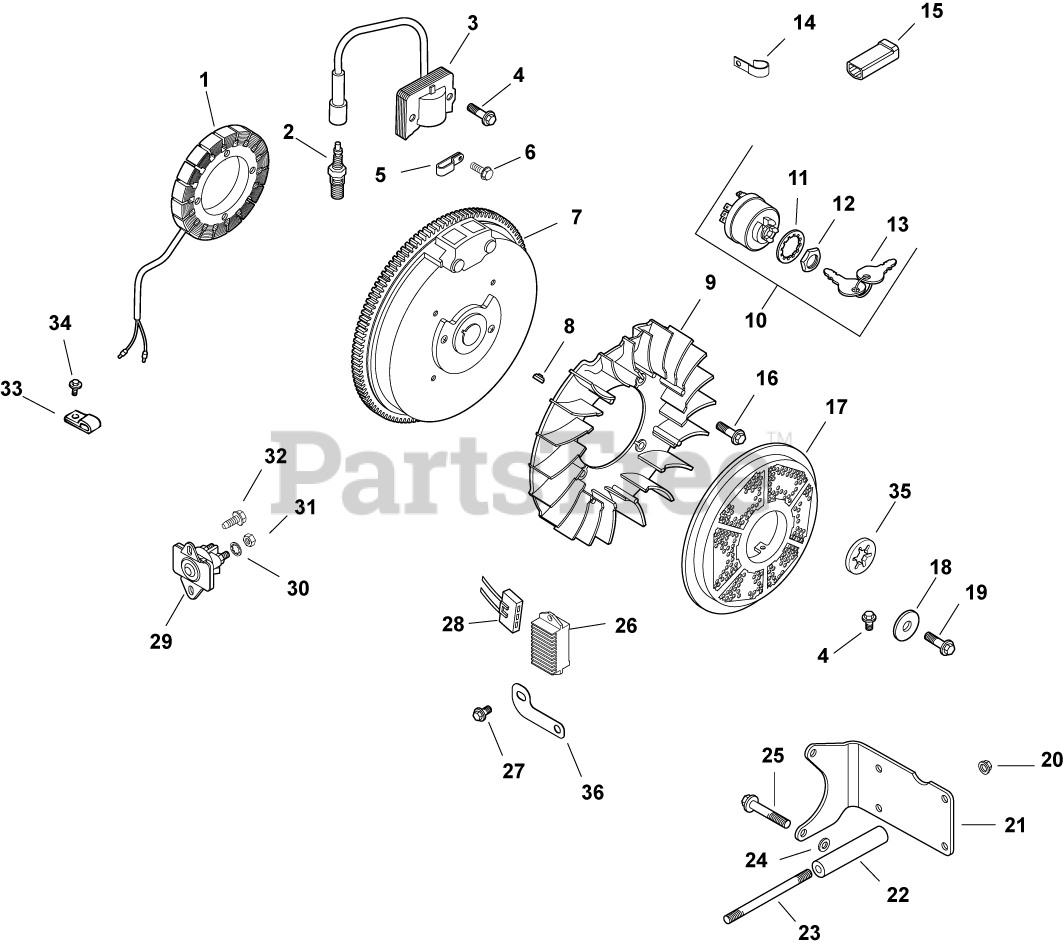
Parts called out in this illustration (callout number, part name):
1	KIT, 15 / 20 AMP STATOR
2	PLUG, SPARK (PRO SERIES)
3	MODULE, IGNITION
4	SCREW, FLG THD FRM M5X.8X20-(#25086399S)
6	SCREW, FLG THD FRM M5X.8X10
7	FLYWHEEL - USE 12 025 72-S
8	KEY, 3/16" X 5/8"
10	SWITCH ASSY, KEY (KM)-USE 25 099 32-S
11	WASHER, INTERNAL TOOTH
12	NUT, KEY SWITCH
13	KEY, SET -USE 48 340 01-S
14	CLIP, CABLE
15	CONNECTOR (1 CONTACT)
16	BOLT, SHOULDER
18	WASHER, FLAT 13/32"
19	SCREW, FLG M10X1.5X45 - (#25086361S)
20	NUT, FLG M8X1.25
21	BRACKET, FUEL TANK
23	STUD, M8X1.25X133-USE 25 755 54-S
24	WASHER, FLAT 11/32"
25	SCREW, FLG M8X1.25X50
26	REG/RECT-15 AMP (KM)-USE 41 403 10-S
27	SCREW, FLG M6X1.0X16
28	CONNECTOR, BODY (KM)-USE 25 155 41-S
29	SOLENOID - WATERPROOF (KM)-USE 25 435 08
30	WASHER, INT TOOTH LOCK 1/4"
31	NUT, JAM 1/4-20 GRADE 2
32	SCREW,FLG THD FRM M6X1.0X16-(#25086397S)
33	CLIP, TUBE & WIRING (KM)
34	SCREW, M5X0.8X25 - (#25086402S)
36	BRACKET, GROUND STRAP
